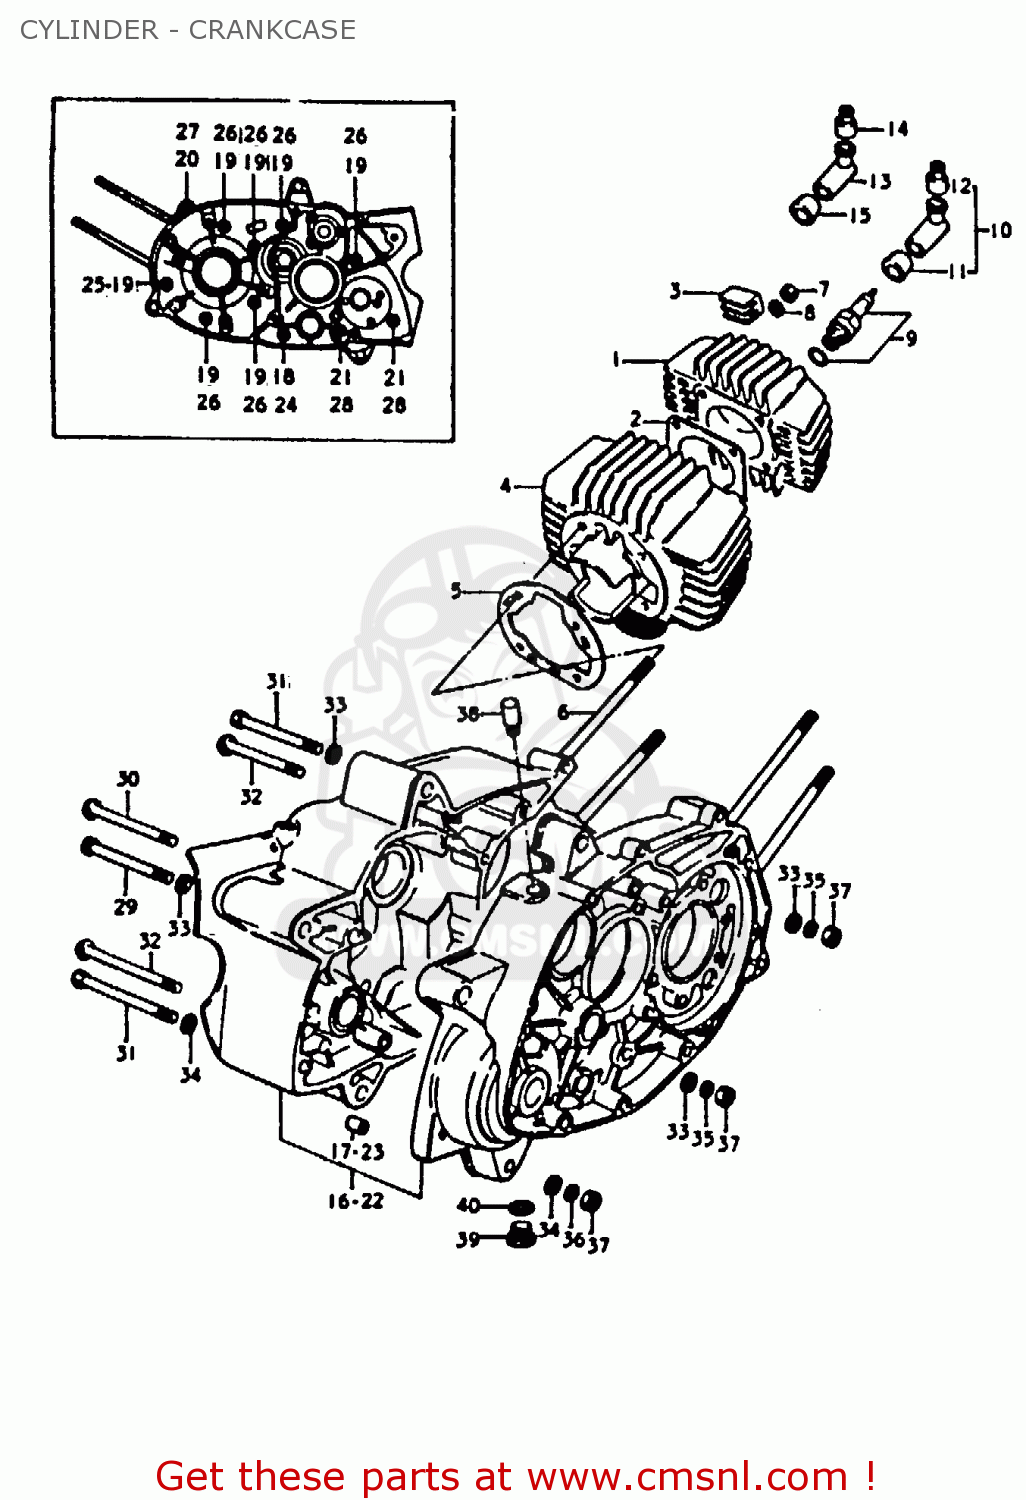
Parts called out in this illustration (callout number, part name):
1	HEAD,CYLINDER
2	GASKET,CYLINDER HEAD (NAS)
3	PAD,CYLINDER
4	CYLINDER
5	GASKET,CYLINDER (MCA)
6	BOLT,STUD
7	NUT (8MM)
8	LOCK WASHER
9	SPARK PLUG
10	CAP,SPARK PLUG
11	SEAL,SPARK PLUG
12	SEAL,SPARK PLU
13	CAP, SPARK PLUG
14	SEAL,SPARK PLUG
15	SEAL, CORD
16	CRANKCASE SET
17	PIN
18	SCREW 6X60
19	SCREW (6X45)
20	SCREW
21	SCREW (6X35)
22	CRANKCASE SET
23	PIN
24	SCREW
25	SCREW
26	SCREW (6X45)
27	SCREW
28	SCREW (6X35)
29	BOLT 8X105
30	BOLT
31	BOLT 8X110
32	BOLT
33	WASHER
34	WASHER
35	LOCK WASHER
36	WASHER,LOCK,8.
37	NUT
39	PLUG
40	GASKET(10X14X3.6) (NAS)
